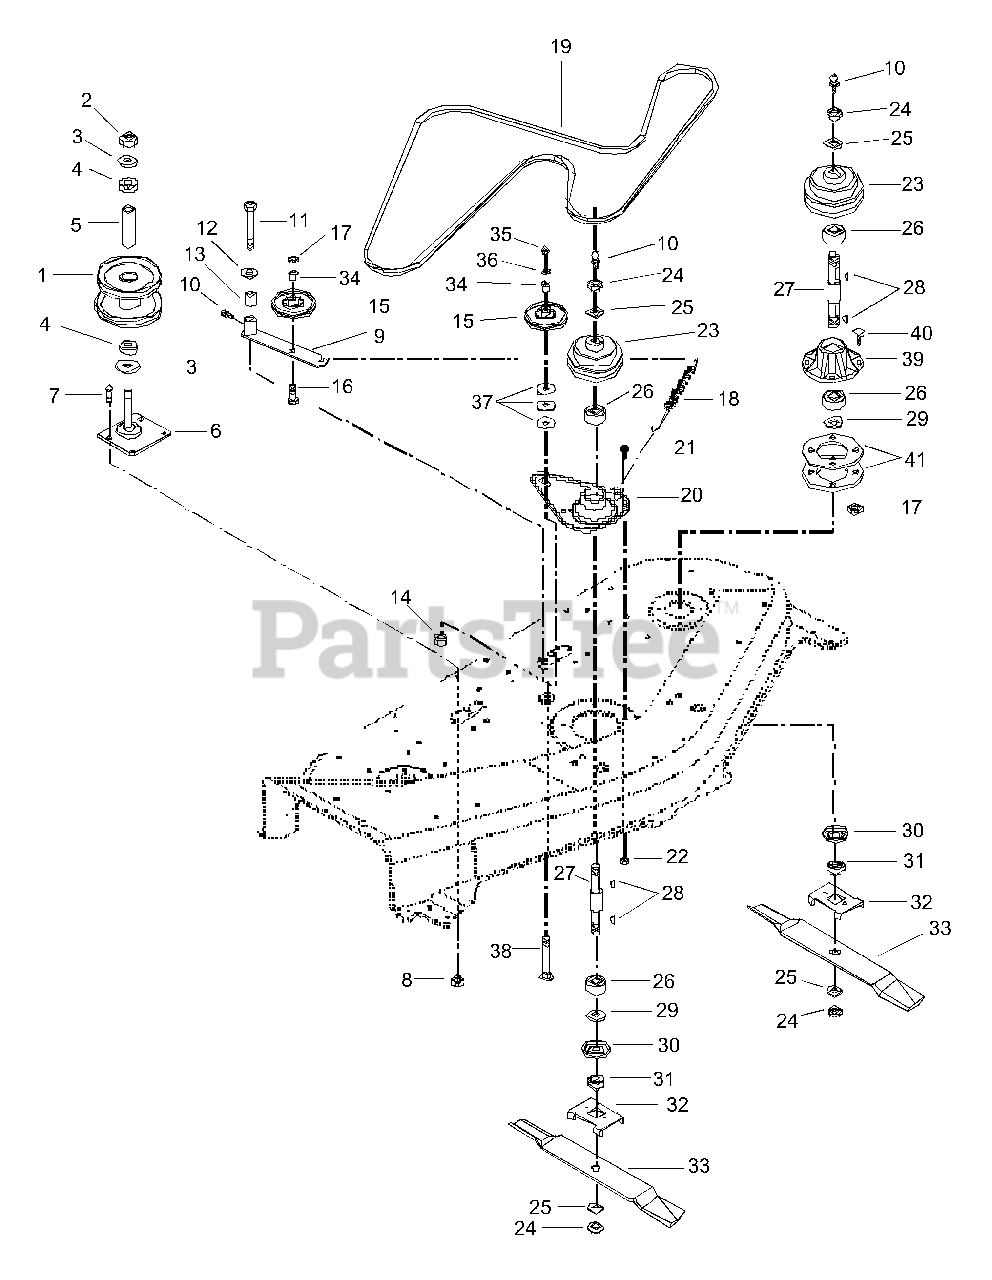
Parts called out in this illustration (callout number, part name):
1	Jackshaft - 48" Deck
2	Nut-Locking-Nylon .625-18
3	Washer-Flat-Steel .630 x 1.005 x .062
4	Bearing-Ball .625 x 1.375 x .44
5	Spacer .640 x .880 x 2.768
6	Plate-Mount
7	Bolt-Round Head Square Neck .31-18 x .62
8	Nut-Locking-Flange .312-18
9	Arm-Idler
10	Fitting-Lube .25-28 x .256
11	Bolt-Hex .500-13 x 2.75 Grade 5
12	Washer-Flat-Steel .505 x .880 x .072
13	Spacer-Pivot
14	Nut-Locking-Center .500-13
15	Idler-Flat 4.00 x .38
16	Bolt-Hex .38-16 x 1.25 Grade 5
17	Nut-Locking-Jam .375-16
18	Spring-Tension
19	V-Belt - 48" Deck
20	Housing Spindle
21	Bolt-Round Head Square Neck .38-16 x .75 Grade 2
22	Nut-Locking Center .375-16
24	Nut-Jam .75-10
25	Washer-Lock .750 x .188
26	Bearing-Ball .750 x 1.781 x .61
27	Spindle Shaft w/Zerk
28	Key-Woodruff .188 x .62 x .25
29	Washer-Flat-Steel .754 x 1.000 x .032
30	Bearing Slinger
31	Retainer Hub
32	Blade Tray 48
34	Spacer-Flanged
35	Nut-Locking-Center .38-16
36	Washer-Flat-Steel .38 x .875 x .083
37	Washer-Flat-Steel .390 x 1.50 x 1.25
38	Bolt-Round Head Square Neck .38-16 x 2.00 Grade 5
39	Spindle Housing
40	Bolt-Round Head Square Neck .38-16 x .75
41	Spacer, Spindle
